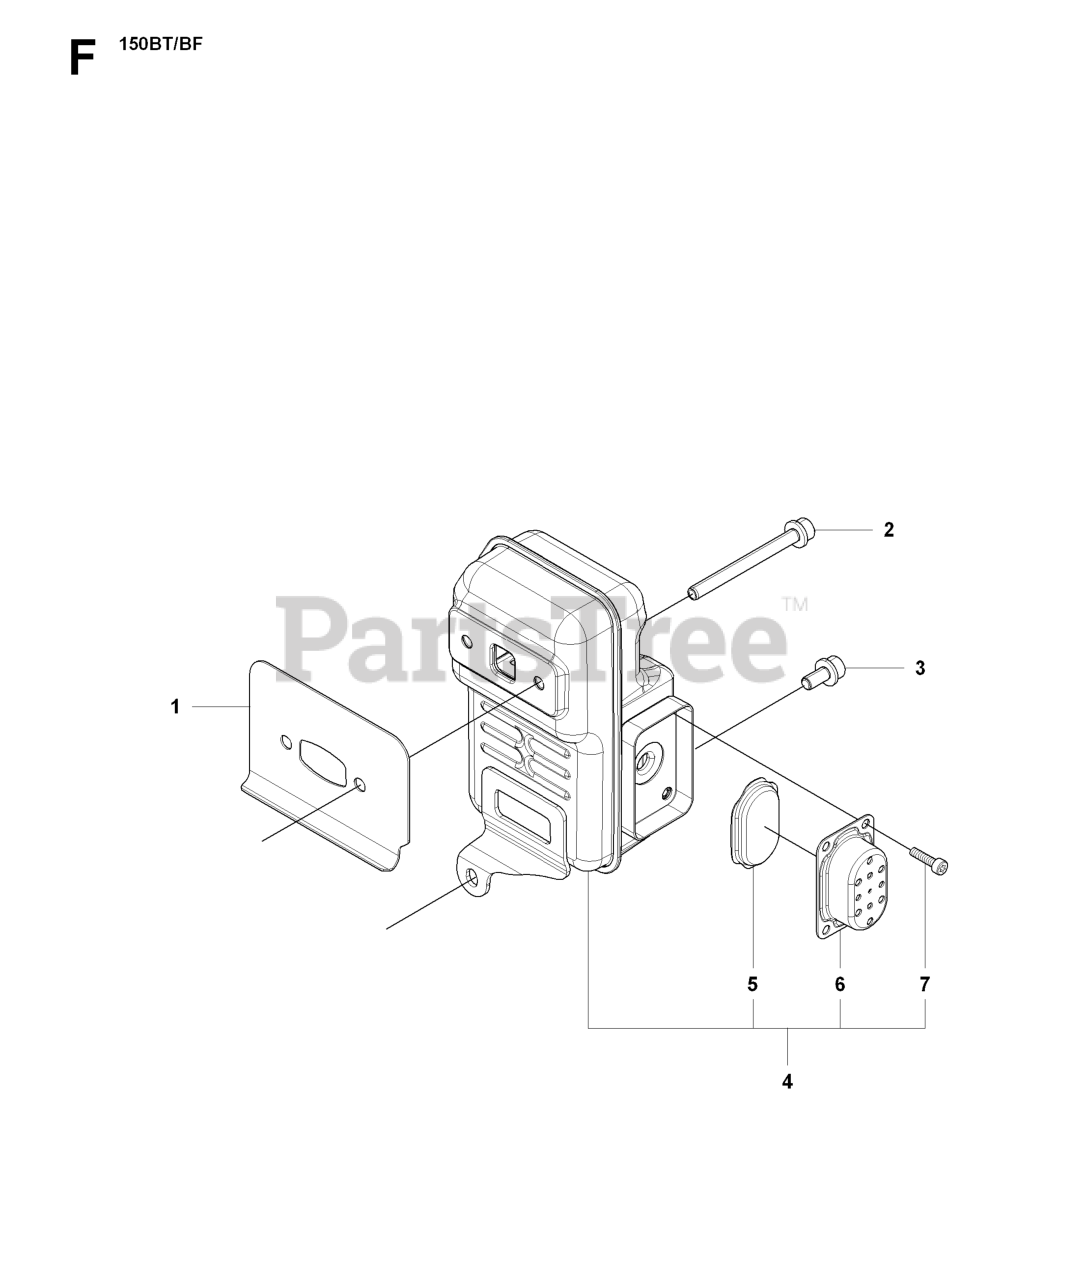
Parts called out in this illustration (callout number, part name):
1	GASKET
3	RP_BOLT
4	MUFFLER ASSY
5	SPARK ARRESTOR SCREEN
6	EXHAUST DUCT
